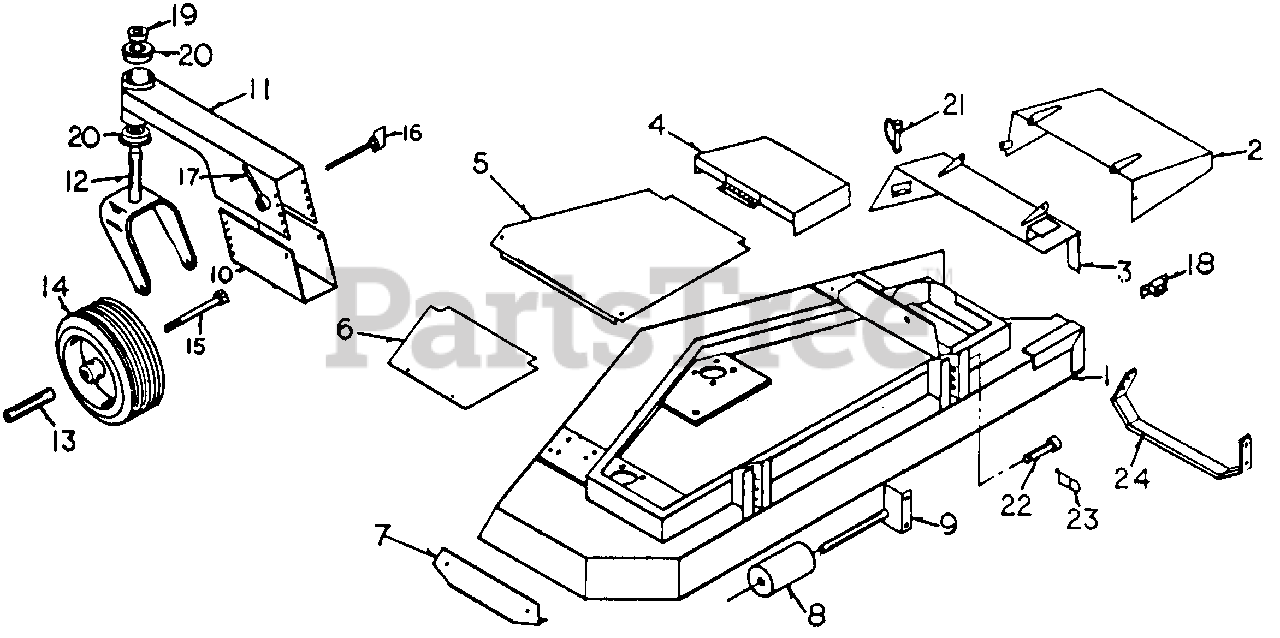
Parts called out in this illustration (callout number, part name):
1	62" Deck
3	Foot Guard Mount
8	Anti-scalp Roller
9	Shaft & Bracket
10	Gauge Wheel Mount Bracket
11	Gauge Wheel Mount
13	Axle
14	Gauge Wheel Assembly
18	10 Amp Circuit Breaker
19	Set Collar, 1"
23	Hair Pin Cotter
24	Shoe, RH
